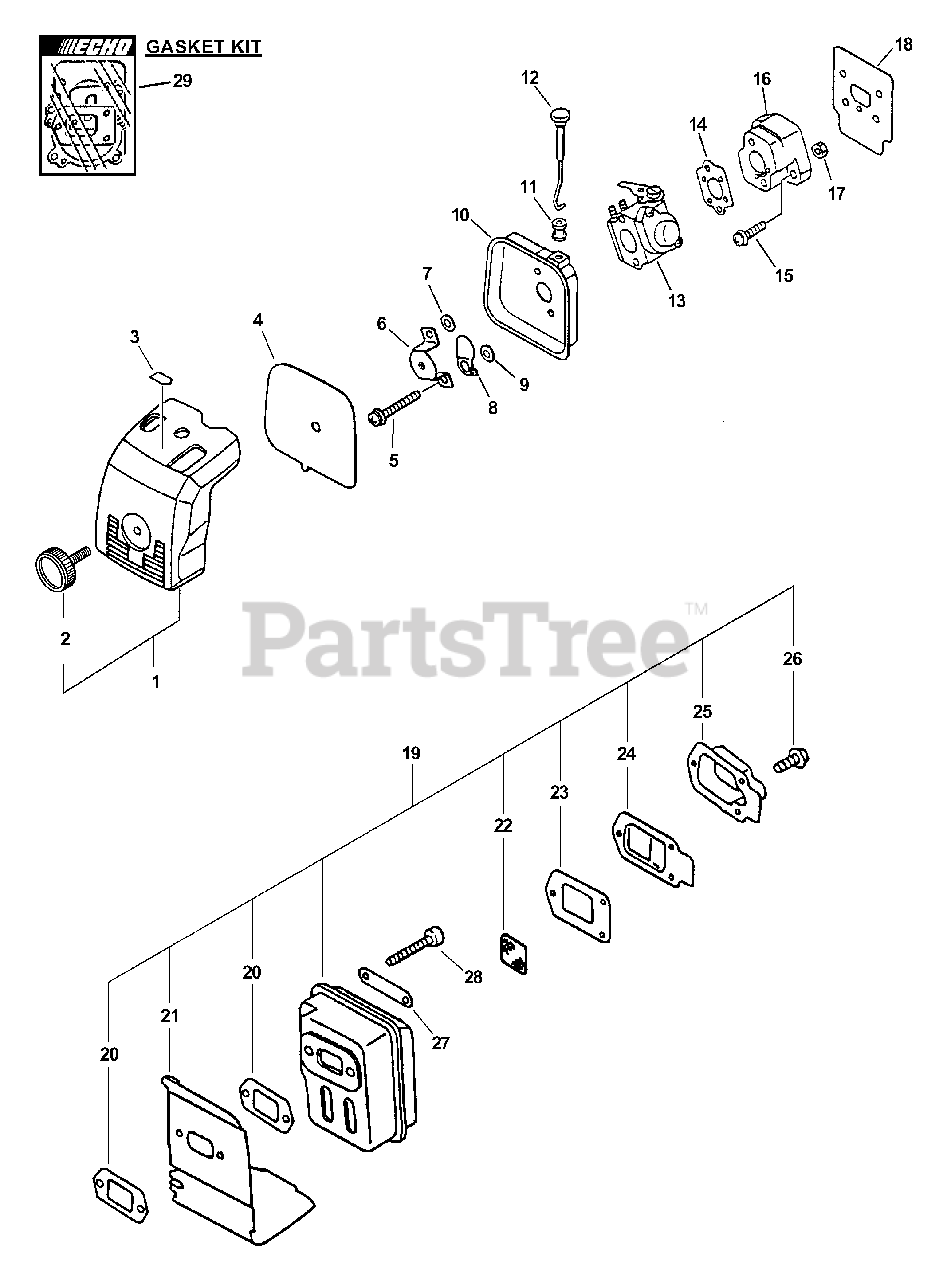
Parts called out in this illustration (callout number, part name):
1	AIR FILTER COVER ASSY
2	THUMBSCREW
3	LABEL - CHOKE
4	FILTER, AIR - HEAVY DUTY
5	SCREW - 5X57
6	PLATE, PREVENT
7	WASHER - 5
8	SHUTTER, CHOKE
9	WASHER - 5
10	CASE, AIR FILTER
12	ROD, CHOKE
13	CARBURETOR WT-424A
14	GASKET, INTAKE
15	SCREW - 5X20
16	INSULATOR, INTAKE
18	SHIELD, INTAKE
19	MUFFLER ASSY
20	GASKET, EXHAUST
21	COVER, MUFFLER
22	SCREEN, SPARK ARRESTOR
23	GASKET, EXHAUST
24	GASKET, EXHAUST - INNER
25	GUIDE, EXHAUST - OUTER
26	SCREW - 4X10
28	SCREW - 5X55
29	GASKET KIT
